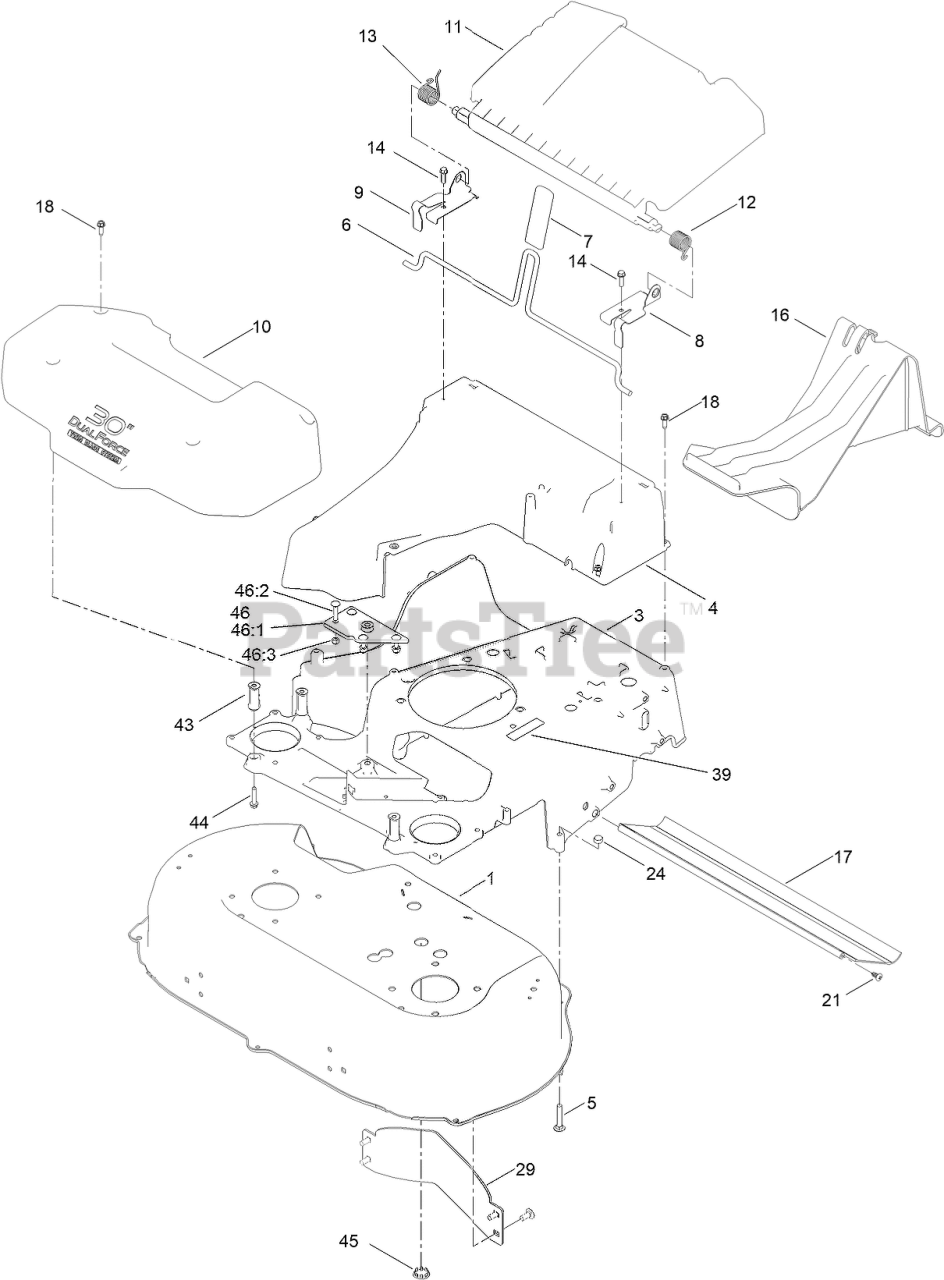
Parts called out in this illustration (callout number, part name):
1	HOUSING ASM
3	FRAME-30IN, 60V
5	BOLT-CAR
6	ROD-RELEASE, HANDLE
7	GRIP-LEVER
8	BRACKET-DOOR, LH
9	BRACKET-DOOR, RH
10	COVER-BELT
11	REAR DEFLECTOR ASM
12	SPRING-TORSION
13	SPRING-TORSION
14	SCREW-HWH
16	PLUG-MULCH
17	SHIELD-TRAILING
18	SCREW-HWHTF
21	SCREW-PTH
24	NUT-LOCK, NI
29	BAFFLE-CONTROL
39	DECAL-PROP 65, SHORT, TRILINGUAL
43	SPACER-FRAME, 30 IN.
44	SCREW-HWHTF
45	PLUG-BUTTON
46	FRAME-PLATE KIT
46:1	PLATE-FRAME, ASM
46:2	SCREW-CARR
46:3	NUT-LOCK, NI
